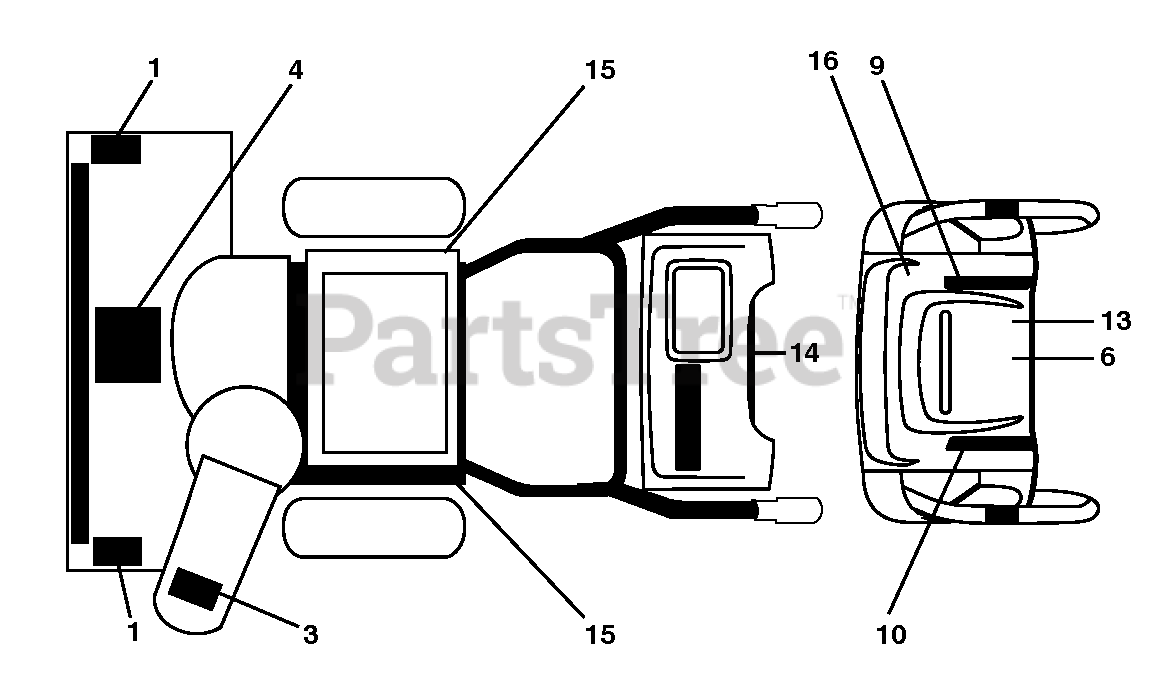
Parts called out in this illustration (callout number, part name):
1	DECAL.AUGER.SAFETY.
3	DECAL.CHUTE.SAFETY.
4	DECAL.AUGER."
9	DECAL CONSOLE DECAL DECAL.SNOW
10	DECAL CONSOLE DECAL DECAL.SNOW
13	DECAL.CONSOLE.HAND.WARMER
14	DECAL CONSOLE DECAL DECAL.SNOW
15	DECAL.BELT.GUARD.
16	DECAL.CONSOLE.HAND.WARMER
